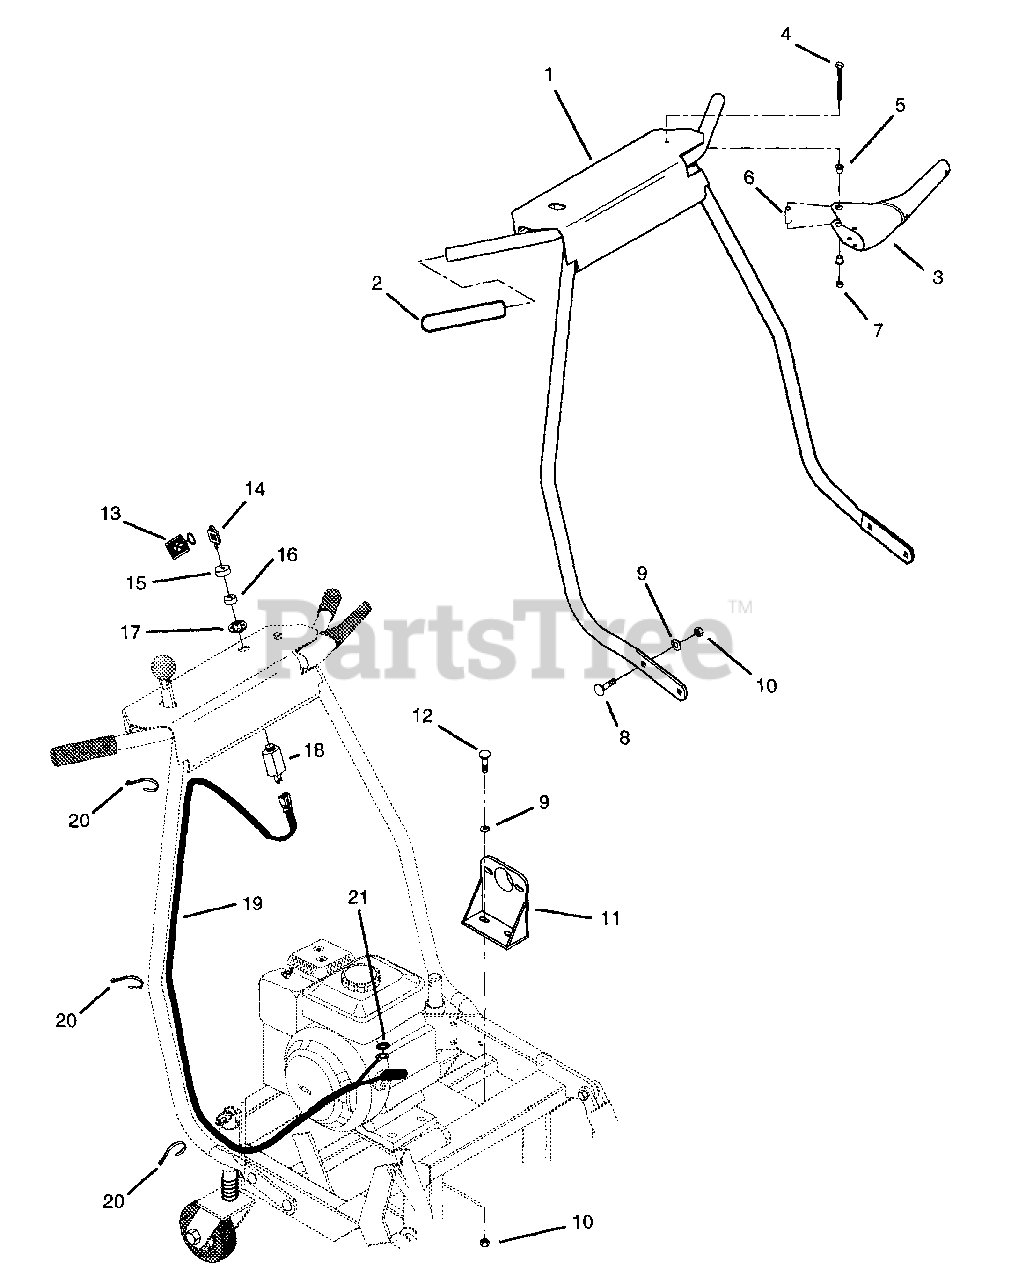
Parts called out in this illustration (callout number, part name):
1	Handlebar Weldment
2	Handle Grip
3	Clutch Lever-Coated
4	Bolt-Hex .31-18 x 2.00 Grade 5
5	Bushing-Flange .320 x .620 x .312
6	Bushing-Sleeve .377 x .503 x .88
7	Nut-Lock Unitorque .31
8	Bolt-Round Head Square Neck .375 x 2.50G5
9	Washer-Lock .375 x .094 Medium Plated
10	Nut-Hex .375-16 Zinc Grade 2
11	Pump Mount Weldment
12	Bolt-Round Head Square Neck .38-16 x 1.25
13	Key Chain
14	Ignition Switch Key
15	Cap-Ignition Switch
16	Nut-Panel .625-32 Greco
17	Washer-Lock Internal .625 x .045 Plated
18	Key Switch Assembly
19	Wire Harness
20	Tie Wrap-Black
21	Washer-Lock External 12 x .025 Plated
